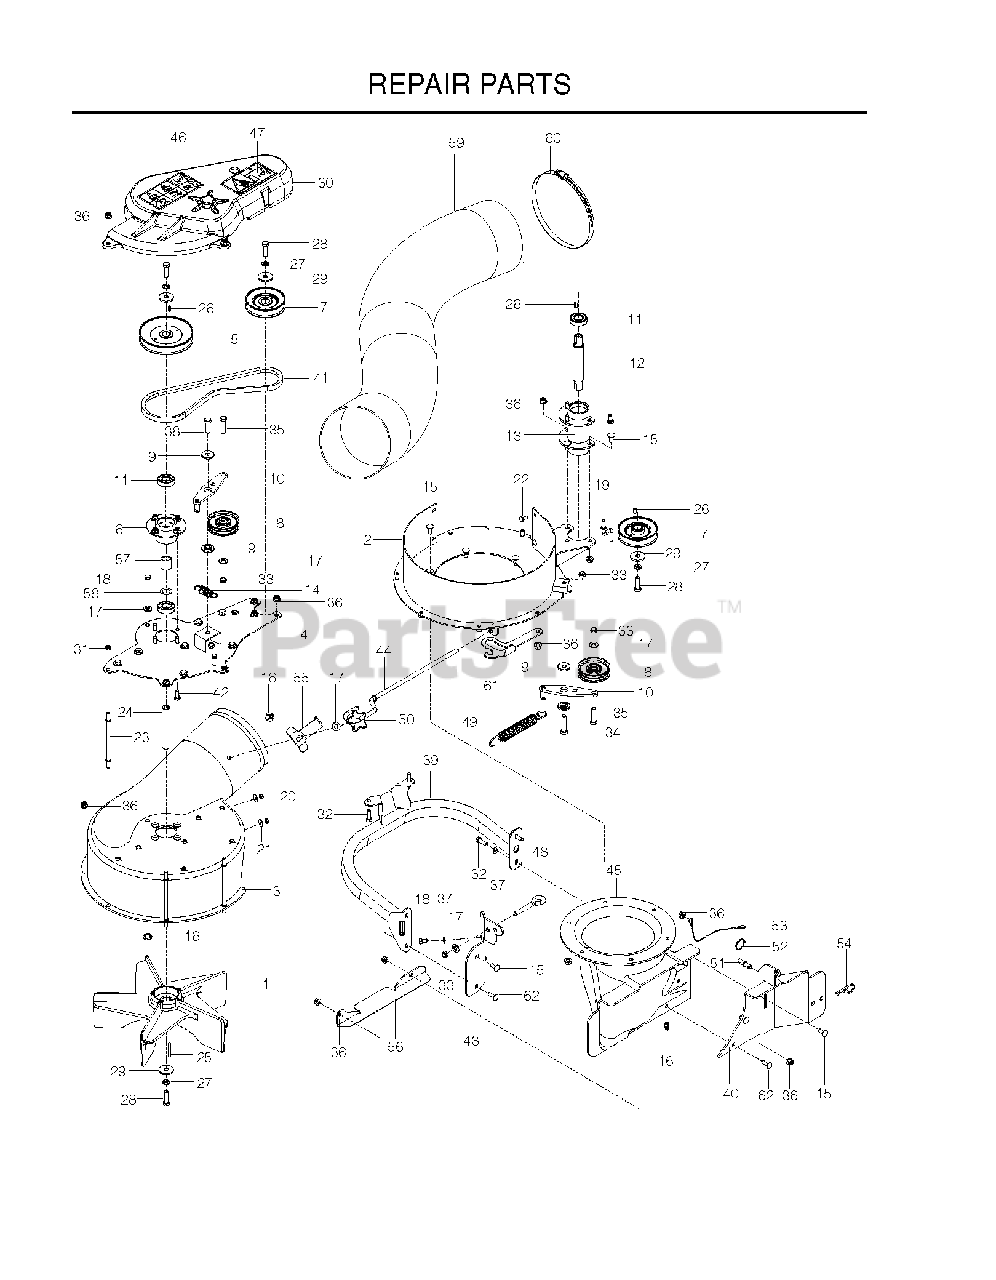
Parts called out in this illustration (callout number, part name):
1	IMPELLER, WELDMENT
2	WELDMENT, BLOWER RING, BLK
3	HOUSING, IMPELLER
4	WELDMENT, TOP PLATE, BLK
6	HUB, BEARING
7	PULLEY, DRIVE
9	BUSHING, BRAKE
10	WELDMENT, IDLER, BLK
11	BEARING
12	SHAFT, SPINDLE
13	WELDMENT, SPINDLE TUBE
14	SPRING, IDLER
15	BOLT 5/16C X 3/4" CARRIAGE
16	NUT 5/16-18 TEE
17	WASHER 3/8 SAE FLAT
18	HCS 5/16-18 X 1/2 GR 5 ZD
19	KEEPER, BELT
20	JAM NUT 1/4C
21	WASHER 1/4 FLAT
22	RHSSNB, 1/4-20X5/8
23	PIN, RETENTION
24	SHAFT, IMPELLER
25	KEY-SQ. 3/16 X 1 1/2
26	KEY, 3/16 X 1/2
27	SLW 3/8 STD
28	BOLT, HEX 3/8-24 X 1.25 GR 8
29	WASHER, HARDENED
30	SHIELD, TOP BELT, W/DECALS
31	NUT 5/16-18 HEX JAM ZD
32	HCS 5/16C X 1
33	NUT HEX 3/8-16 NYLON, THIN
34	BOLT, HCS 3/8-16X1-3/4
35	HCS 3/8C X 1 1/2
36	5/16-18 NYLOC FLANGE NUT
37	FLAT WASHER 5/16 SAE
38	HCS 3/8C X 1 1/4 GR5
39	GUARD, RUB, BLK
40	MOUNT, REAR, BLK
41	BELT-TRANS
42	HCS 5/16C X 3/4
43	BRACKET, MOUNT, FT-BLK
44	PIN, MOUNT
45	HOUSING, BLOWER
46	DECAL, EURO WARNING
47	EURO DECAL, IMPELLER
48	EYE BOLT
49	SPRING, DECK DRIVE
50	KNOB, 5/16-18 X 1/2
51	PIN, MOUNT
52	RETAINER
53	LANYARD
54	HAIRPIN #4
55	BRACKET, RETAINER, BLK
56	BRACKET, DIVERTER BLK
58	WASHER .787 X 1.125 X .06
59	HOSE 7 X 54 CLEAR
60	CLAMP, HOSE
61	LATCH, PIN, BLK
62	RHSNB 5/16C X 1
